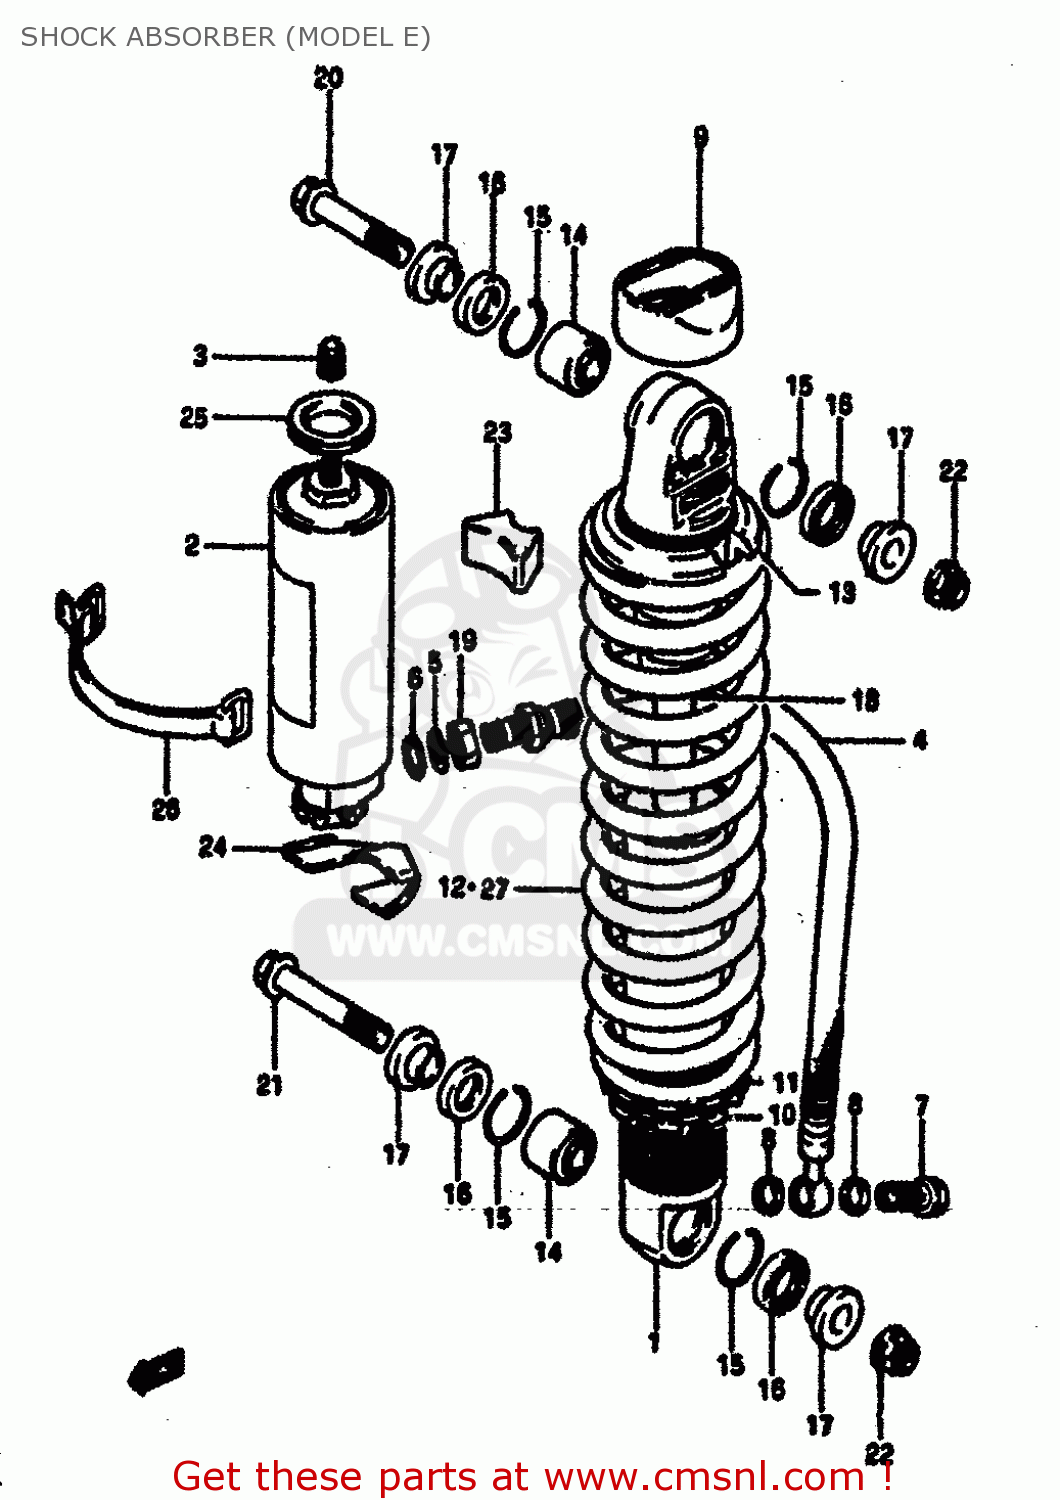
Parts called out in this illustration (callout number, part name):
1	ABSORBER ASSEMBLY,REAR SHOCK
2	RESERVE TANK,REAR SHOCK
3	CAP
4	HOSE,REAR SHOCK ABSORBER
5	WASHER,REAR SHOCK HOSE
6	O-RING,RESERVE TANK
7	BOLT,REAR SHOCK ABSORBER
8	GASKET (NAS)
9	CLIP
10	GUIDE,REAR SHOCK ABSORBER SPRING
11	GUIDE,SPRING
12	SPRING
13	GUIDE,REAR SHOCK ABSORBER SPRING
14	BEARING,REAR SHOCK ABSORBER
15	RING
16	SEAL,DUST
17	SPACER
18	ROD,PISTON
19	NUT 12MM
20	BOLT,REAR SHOCK ABSORBER
21	BOLT(10X52)
22	NUT
23	CUSHION,RESERVOIR TANK
24	CUSHION,RESERVOIR TANK
25	CUSHION,RESERVOIR TANK
26	BAND
27	SPRING
